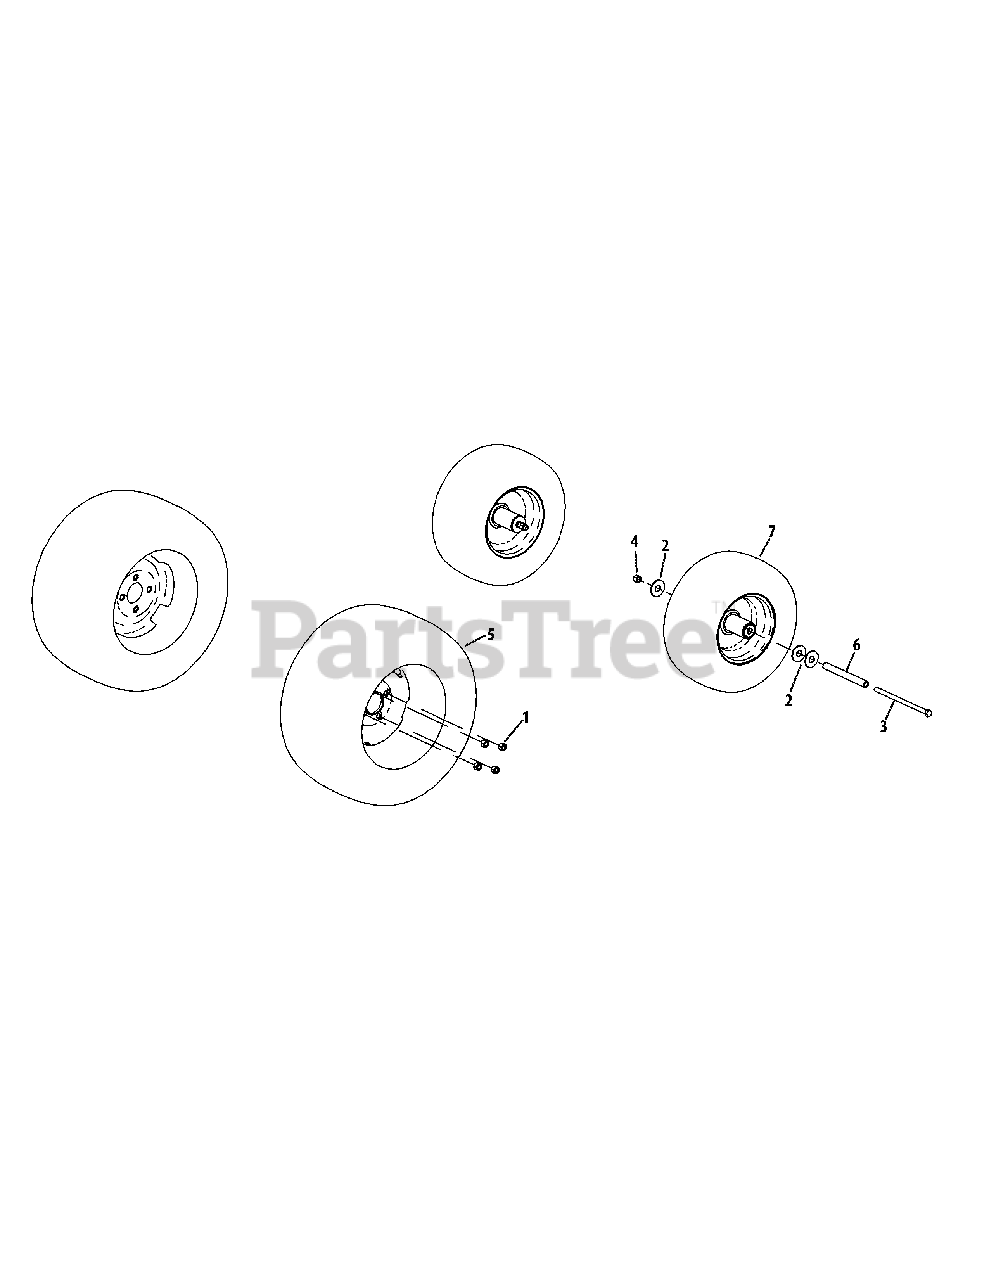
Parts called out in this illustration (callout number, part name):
1	Lug Nut, 1/2-20
2	Washer, .781 x 2.00 x .105
3	Hex Screw, 1/2-20 x 9.50
4	Nut, 1/2-20, Lock
5	Wheel Assembly, 24 x 12.00-12
5	Tire, 24 x 12.00-12, Turf Master
6	Spacer, .51 x .75 x 7.49
7	Front Wheel Assembly, 16 x 6.50-8
7	Tire, 16 x 6.50-8
